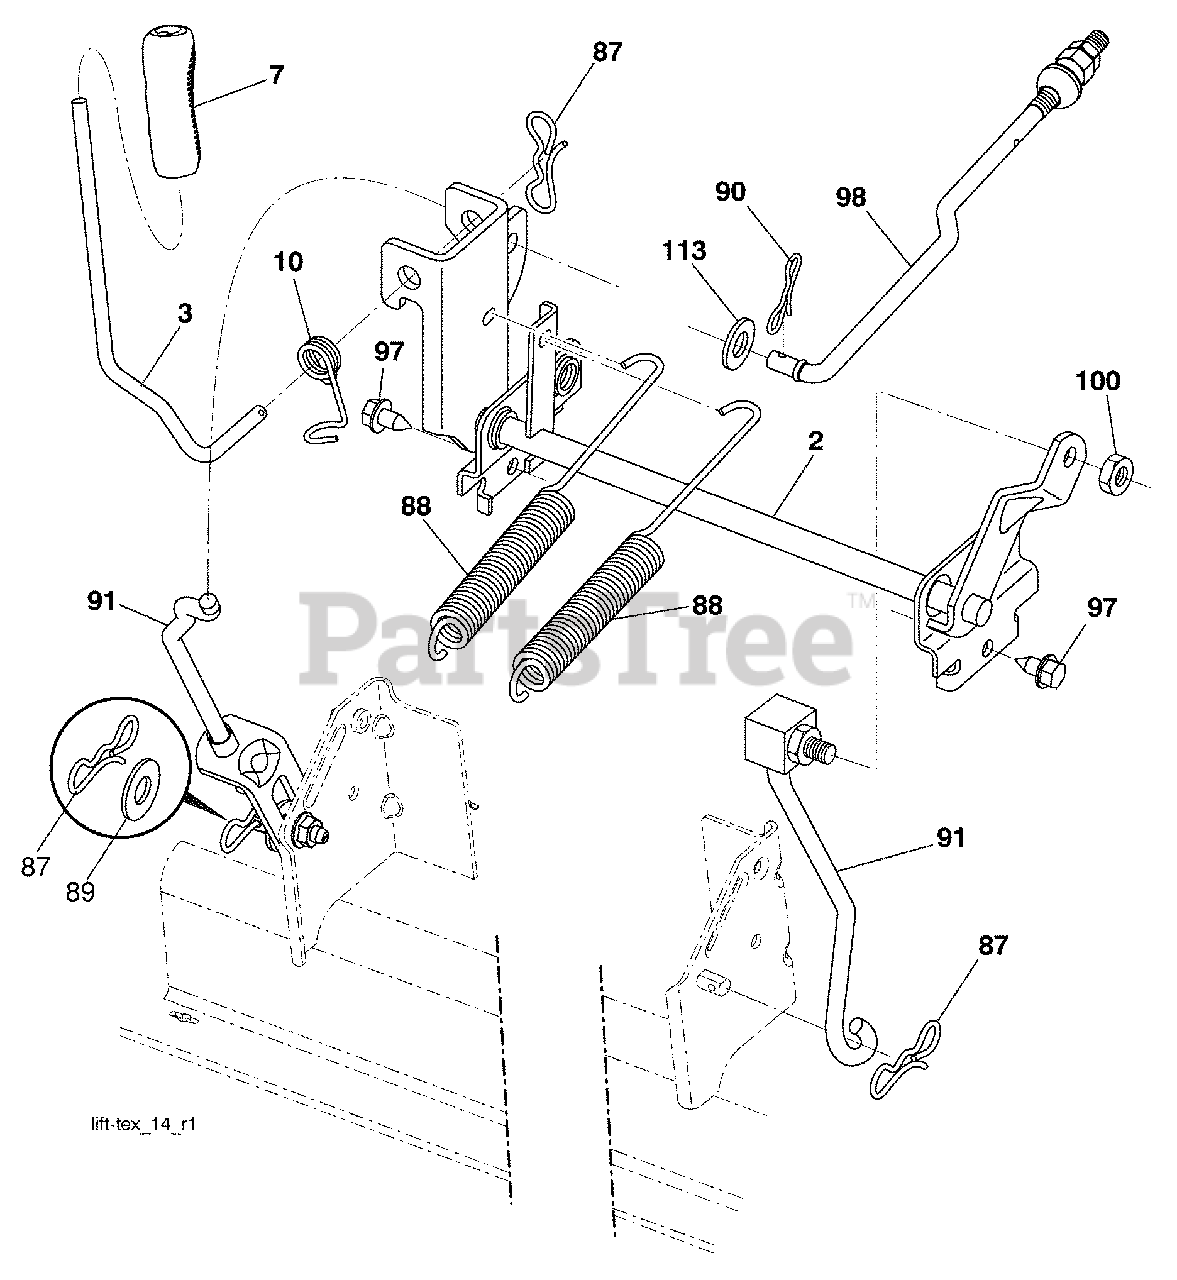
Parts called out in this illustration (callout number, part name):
2	Shaft Asm., Lift
3	Lever Asm., Lift RH
7	Grip, Lever
10	Spring Torsion
87	Pin Cotter 7/16 Bow Tie Lock
89	Washer Clear Zinc
90	Pin Cotter 5/16 Bow Tie Lock
91	Link Asm Lift LH Rear
97	Screw Hex Wsh. THDR 3/8-16 x 3/4
98	Link Lift Susp. Front Mower
100	Nut Centerlock 3/8-16 unc
113	Washer 17/32 x 1-3/16 x 12 Ga.
